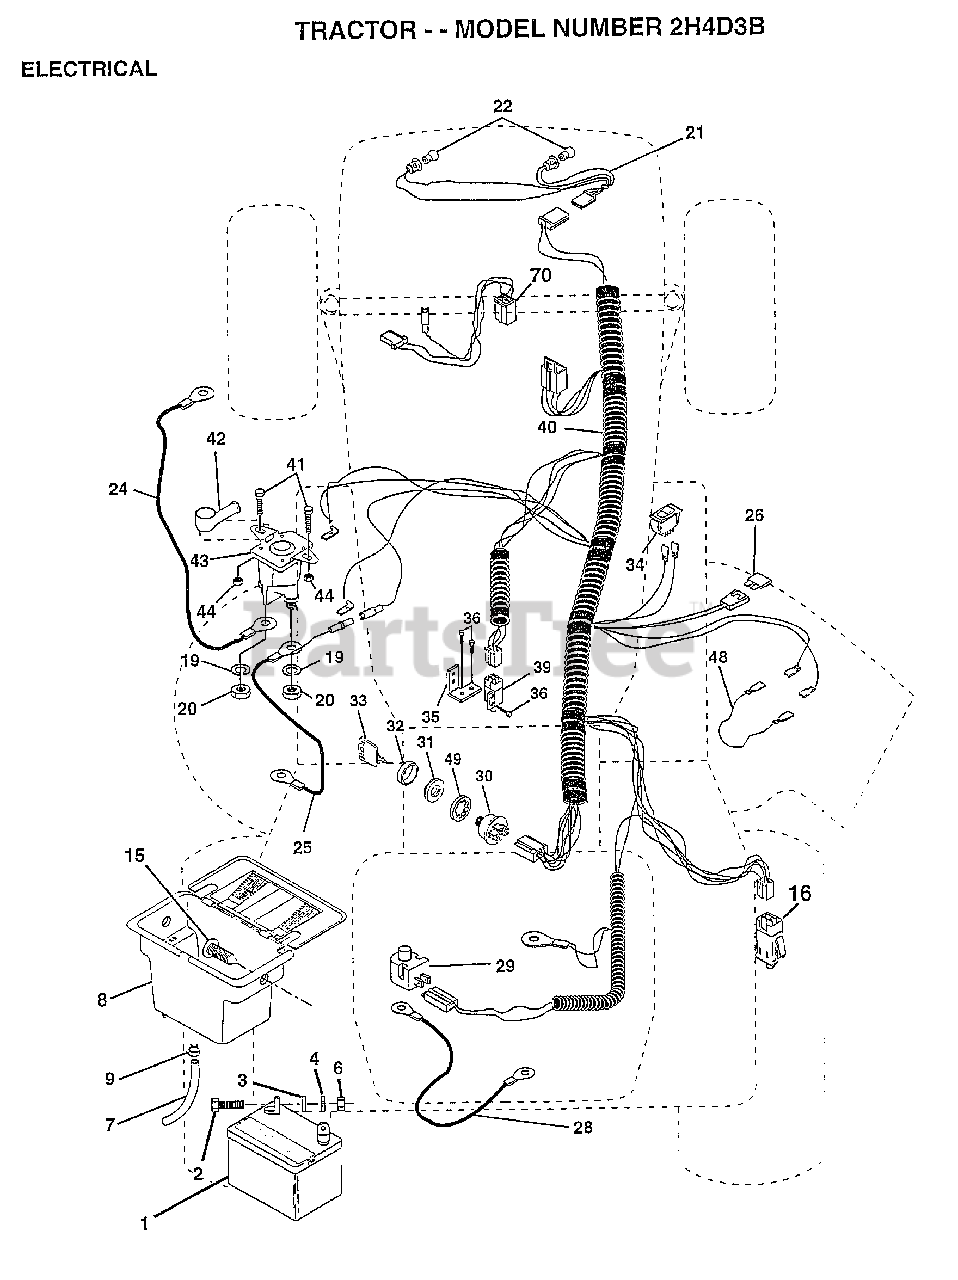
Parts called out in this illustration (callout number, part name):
2	BOLT LT
3	WASHER
4	LOCKWASHER
7	TUBE T
8	HOSE CLAMP T
15	FASTNER.SNAP-IN
16	SWITCH INTERLOCK
20	NUT
21	"HARNESS,LIGHT SOC"
22	HEADLAMP BULB
24	CABLE.BTRY.6GA.RD
25	CABLE.BTRY.6GA.38
26	FUSE HYT
28	CABLE T
29	SWITCH SEAT
32	COVER KEY SWITCH
33	KEY MLD GEN DELTA
34	SWITCH LT
35	BRACKET LT
36	SCREW
39	SWITCH INTERLOCKT
40	HARNESS.IGN.DASH.
41	BOLT HXHD FIN
44	NUT HXKEP 1/4X20
48	ADAPTER AMMETER
49	WASHER PINNED
70	HARNESS ENG DUAL
